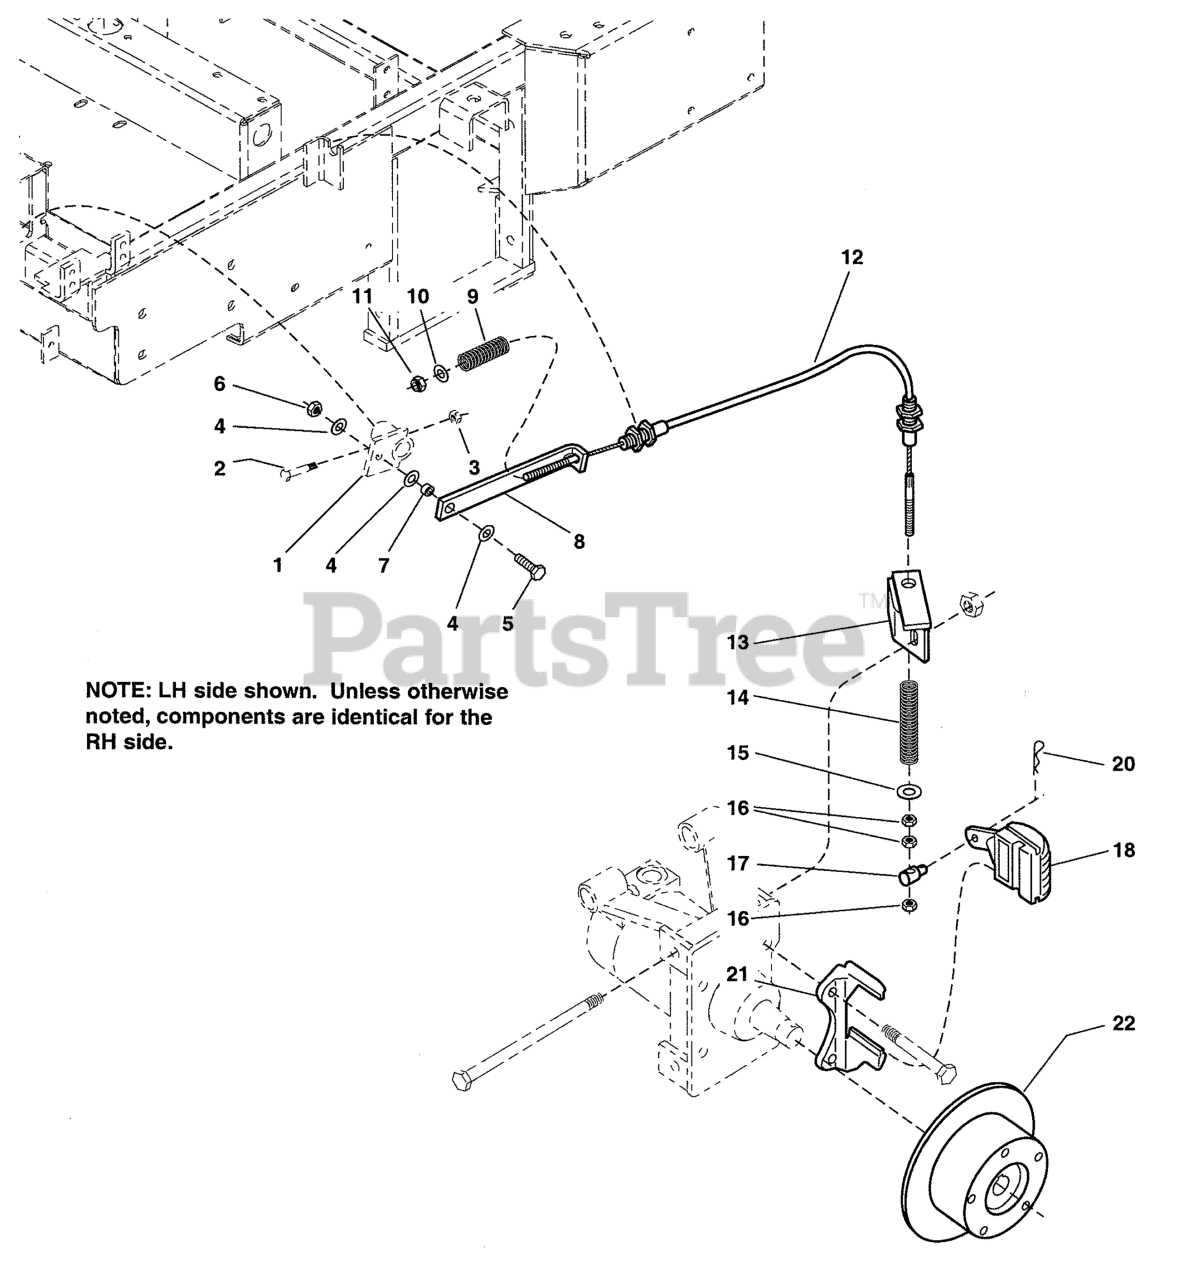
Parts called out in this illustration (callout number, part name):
1	BRAKE LINKAGE PIVOT
4	WASHER, 3/8 SAE
5	BOLT, 3/8-16 X 1-1/4" GD5 CZ
6	NUT, 3/8-16 HEX NYLON LOCK
7	SPACER, Pivot
8	LINK, Brake Lock
9	SPRING, Compression
10	WASHER, 5/16" SAE
11	NUT, 5/16-24 HEX NYLON LOCK
12	CABLE, Brake
13	BRACKET, Cable Mount-LH
14	SPRING, Compression
15	WASHER, Fender, 5/16
16	NUT, Hex, 5/16-24
17	ADJUSTER, Brake Linkage
18	BRAKE CALIPER, LH
20	HAIRPIN CLIP
21	MOUNT, Brake Caliper
22	HUB, 8" Brake Disc
